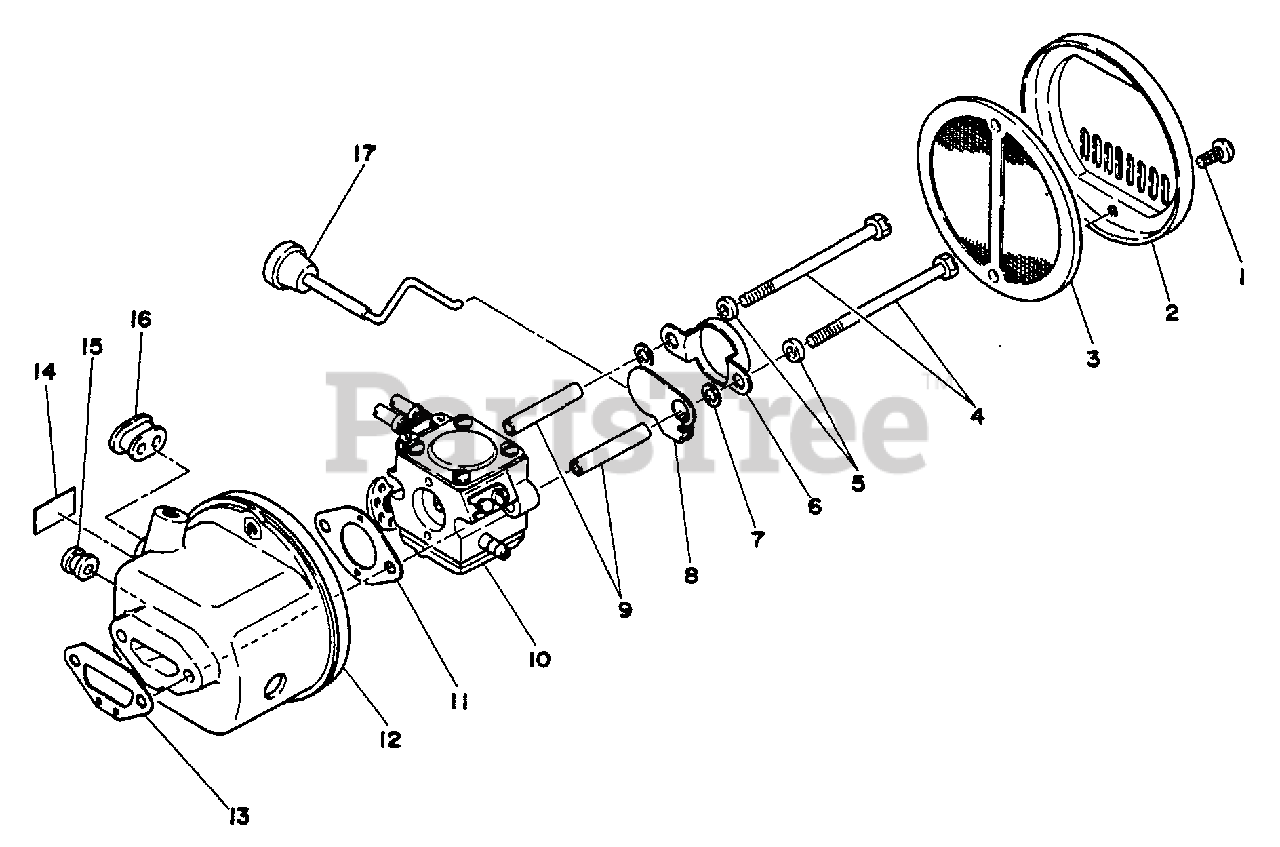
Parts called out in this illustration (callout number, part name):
1	SCREW - 4X10
2	COVER, AIR FILTER
3	FILTER, AIR
6	PLATE, PREVENT
7	WASHER
8	SHUTTER, CHOKE
9	SPACER
10	CARBURETOR WA-21
11	GASKET, INTAKE
12	CASE, CARBURETOR
13	GASKET, INTAKE
14	LABEL - FUEL ADJUST
17	ROD, CHOKE
